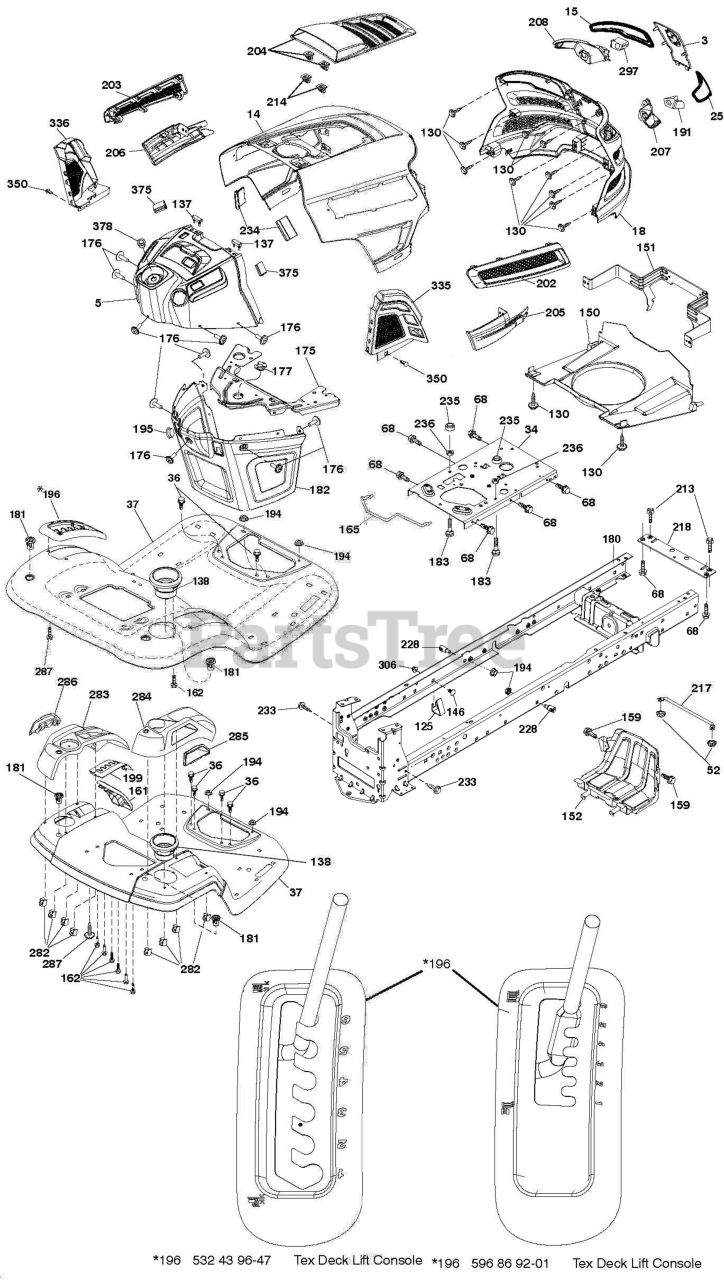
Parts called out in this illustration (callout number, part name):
3	APPLIQUE.SUBASM.GT.HUSQ.II
5	DASH.UPR.ASSY.GT2.SRVMNDER.PTO
5	DASH
5	Dashes
5	DASHBOARD.UPPER.ASM.GT2.498
14	DASH.UPR.ASSY.GT2.SRVMNDER.PTO
14	KIT.HOOD.ASM.HUSQ.GT.TEX.668
15	LENS.HEADLIGHT.LH.GTII.2011
18	GRILLE.SUBSTRATE.2011.
25	LENS.HEADLIGHT.RH.GTII.2011
34	PLATE.ENGINE.WELDED.CHASSIS
36	SCREW 5/16"
37	FENDER.TLT.W/CPH.W/FW.ORANGE
37	FENDER.TLT.FS.W/CPH/FW/RSF.ORN
37	FENDER.TLT.PDL.CNTRL.W/CPH.ORG
58	DRAWBAR UPPER 2PC SMALL FENDER
125	CLIP.FUEL.LINE
137	BUMPER DASH
138	HOLDER.CUP.LT.GREY
146	BOLT.RDHD.SHT.SQNK.3/8-16X5/8
150	AIR.DUCT.GTV.BLACK
151	BRACKET.PIVOT.HOOD.GT.HUSQ.II
152	SHIELD.BROWNING.PNT.GT.V2
159	BOLT.HEX.HD.WASHER.5/16-18X.75
159	SCREW 3/8-16X1
159	SCREW
161	WINDOW.FUEL.LT.HUSQ.TEX.498
162	SCREW.HI-LO.CONSOLE
165	SUPPORT.TANK.REAR.W/TEX
175	PLATE.PNT.CROSSMEMBER.HUSQ/PRE
176	SCREW.#10-24X5/8.RN.QU
177	BUSHING STEERING
180	CHASS.WLDMNT.TL.12GA/2P.48/54
181	BUSHING.MNT.FEND.CRGO.TEX.49
182	DASH.LOWER.COMMON.12V.ADAPTOR
183	BOLT.5/16-18X1-1/4 FULL THD
189	SCREW
189	BOLT.HEX.HD.WASHER.5/16-18X.75
189	SCREW, 3/8-16X3/4
191	INSERT.REFLECTIVE.RH.HUSQ.GTII
194	NUT LOCK HEX FLANGE 5/16-18
195	PLUG.HOLE.DASH.LOWER.12V.BLK
199	PLATE.DECK.LIFT.HUSQ.LT
202	VENT.SIDE.RH.GT.HUSQ.II.
203	VENT.SIDE.LH.GT.HUSQ.II.498
204	VENT.TOP.ASM.HUSQ.GT2
204	VENT.ASM.TORPHD.HUSQGT.LOGO.CL
205	SIDE.TRIM.RH.GT.HUSQ.II
206	SIDE.TRIM.LH.GT.HUSQ.II.GRAY
207	HEADLIGHT.CUP.BEZEL.HUS.GT2.RH
208	HEADLIGHT.CUP.BEZEL.HUS.GT2.LH
213	BOLT
213	SCREW HEXAGON HEAD SCREW 5/16-
214	CLIP.RETAINER.TINNER.
217	ROD.PIVOT.HOOD
218	X-PIECE.HOOD.STOP.NON/
228	STUD.W/"D"ANTI-ROTATION
233	BOLT.SHOULDER
234	BUMPER.HOOD.TEX.HUSQVARNA
235	SPACER FENDER
236	NUT.CENTERLOCK.5/16-
282	CLIP.RETAINER.CONSOLE.LT.HUSQ
283	CONSOLE.DECK.LIFT.R.SDFL.HUSQ
283	CONSOLE.ASM.LFT.RSF.HUSQ.LT
284	CONSOLE.SHFT.PDL.CNTRL.HUSQ.LT
284	CONCOLE.CNTRL.PDL.HUSQ.LT.498
285	CONSOLE INSERT RH
286	CONSOLE.INSRT.LH.HUSQ.LT.BLACK
287	SCREW 1/4X20
297	INSERT.REFLECTIVE.LH.HUSQ.GTII
306	NUT LOCK FLG 3/8-16 UNC
335	COVER.LOWER.DASH.RH.BLACK
336	COVER-LH.LOWER.DASH.GT2.BLACK
350	CLIP.X-MAS.TREE
375	BUMPER CLIP-ON. DASH 1"
378	BUSHING FLANGE; PLASTIC
